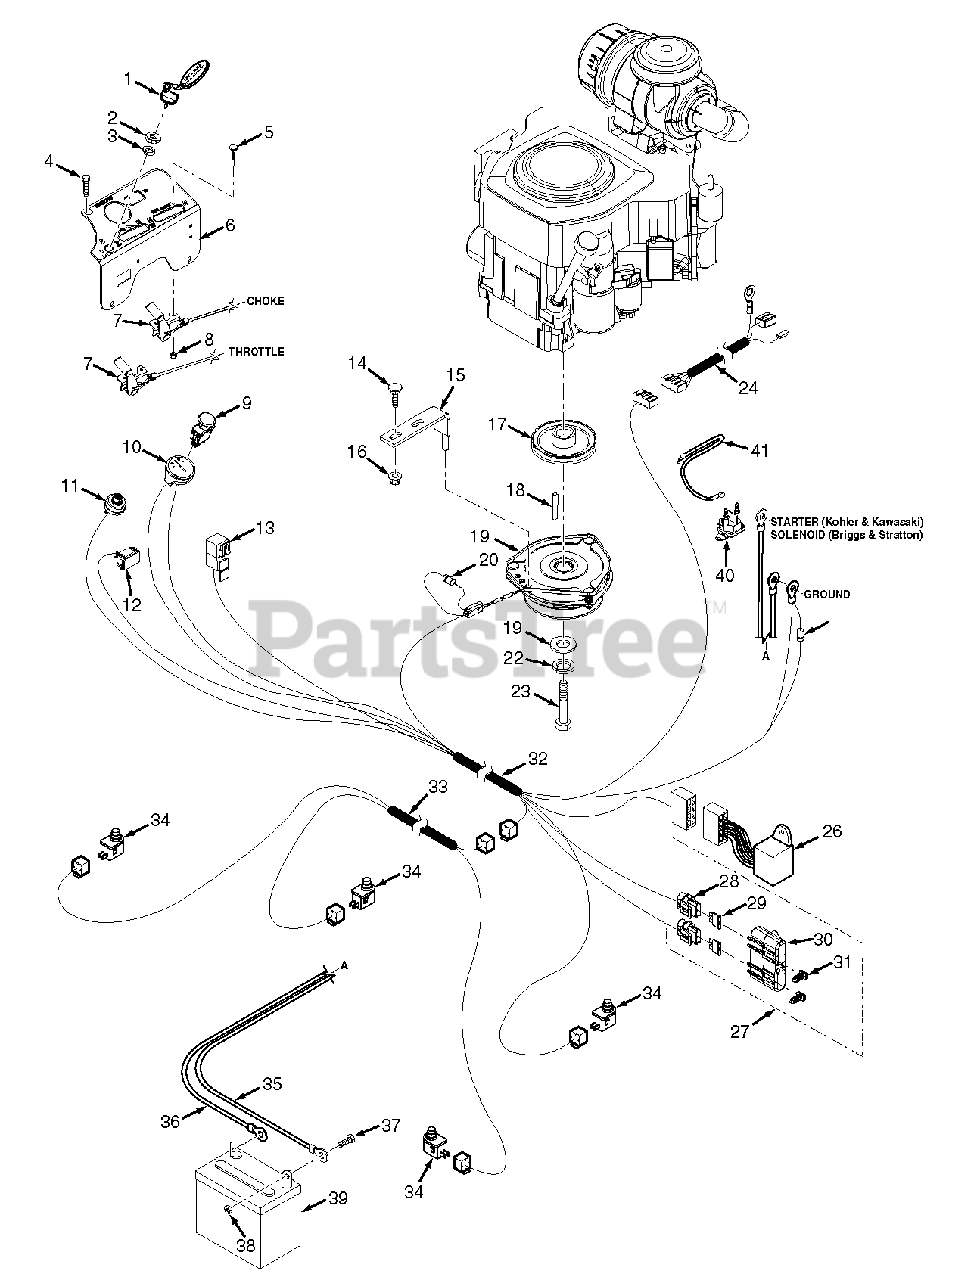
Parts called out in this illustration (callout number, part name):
1	Key, Ignition
1	Key Assembly w/Fob
2	Nut, Hex 5/8-32
3	Lockwasher, 5/8" Internal
4	Bolt, Hex Head Serrated Flange 1/4-20 x 1/2"
5	Bolt, Carriage #10-24 x 1/2"
6	Instrument Panel w/Decal
7	Control Cable
8	Locknut, #10-24
9	Switch, PTO
10	Ammeter
11	Switch, Starter
12	Hourmeter
13	Relay
14	Bolt, Carriage 5/16-18 x 3/4"
15	Anti-Rotation Weldment
16	Nut, Flange Elastic Stop 5/16-18
17	Pulley, 5" Dia. - 1.125 Bore
18	Key, 1/4 x 1/4 x 3-1/2"
19	Clutch, GT3.5 - 1.125 Bore
20	Diode, 600V - 6A
21	Flatwasher, 7/16-.469 x 1.75 x .25
22	Lockwasher, 7/16" Spring
23	Bolt, Hex Head 7/16-20 x 2-1/4" w/Patch
24	Wire Harness Adapter, Kawasaki
24	Wire Harness Adapter, Kohler
24	Wire Harness Adapter, Briggs & Stratton
25	Diode
26	Electronic Module
27	Double Fuse Assy.
28	Fuse Holder
29	Fuse, 20 Amp
30	Cover, Sealed Double
31	Clip, Wire
32	Wire Harness, SCZ48/52
33	Wire Harness, Operator Platform
34	Switch
35	Battery Cable, 25" Red (Kawasaki)
36	Battery Cable, 27" Black
37	Bolt, Hex Head 1/4-20 x 1/2"
38	Nut, 1/4-20 UNC
39	Battery, 350 CCA
40	Solenoid, Sealed (Briggs & Stratton)
41	Battery Cable, Red 9" (Briggs & Stratton)
